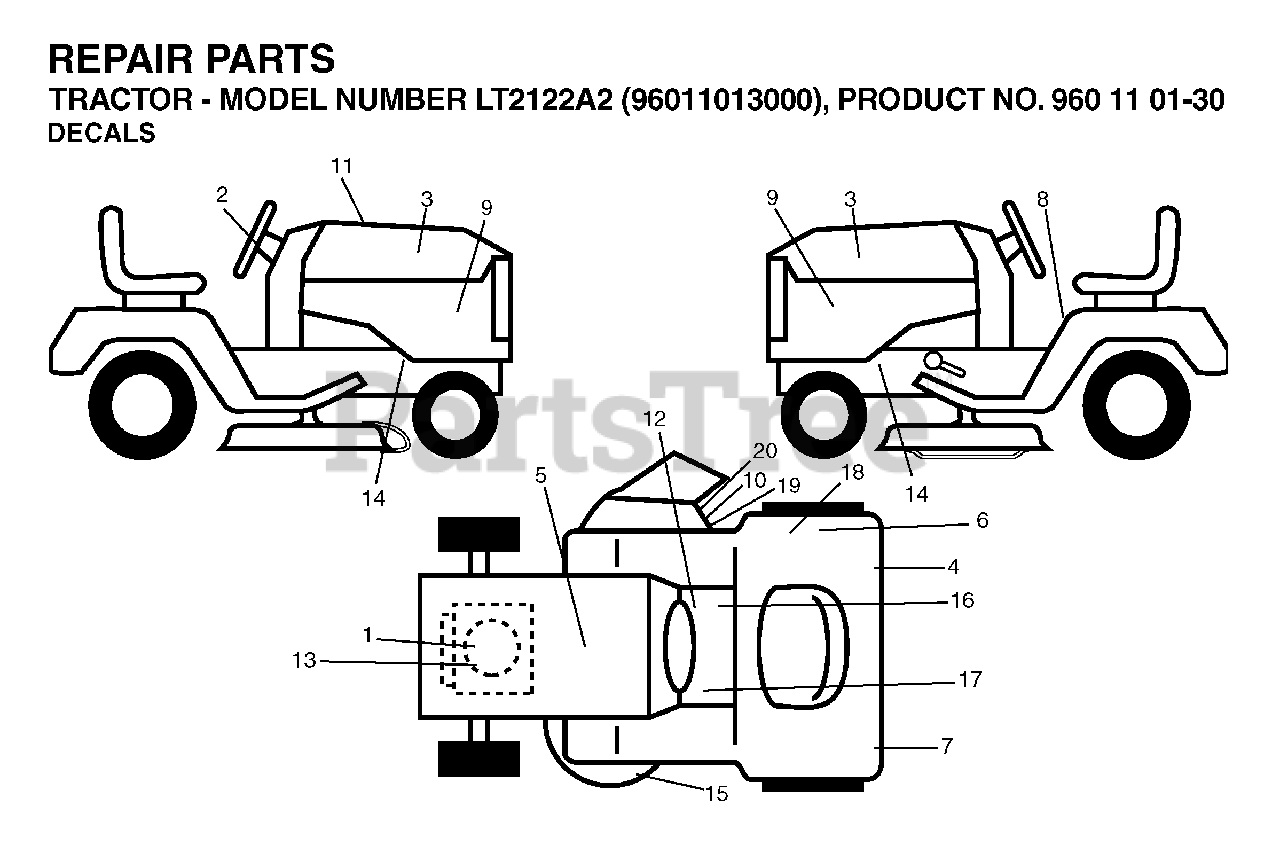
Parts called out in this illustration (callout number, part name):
5	DECAL BTRY SYMBOLS
6	DECAL.FENDER
10	DECAL.INTERNATIONL.CUTFINGER
12	DECAL PARK BRAKE
15	DECAL V-BELT SCHEMATIC
19	DECAL, DEFLECT WARNING
